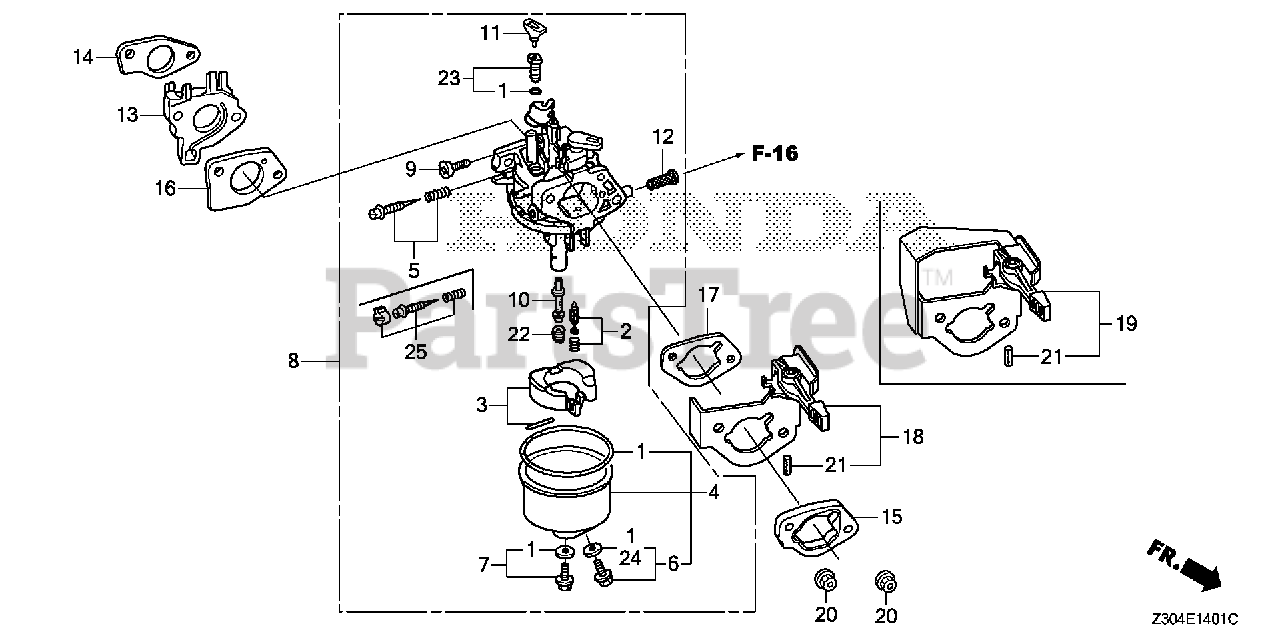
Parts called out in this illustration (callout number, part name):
1	GASKET SET
2	VALVE SET, FLOAT
3	FLOAT SET (CARBURETOR NO.)
4	CHAMBER SET, FLOAT
6	SCREW SET, DRAIN (Honda Code 1672187). (CARBURETOR NO.)
7	SCREW SET
8	CARBURETOR ASSY. (BE95L A)
9	SCREW, THROTTLE STOP
10	NOZZLE, MAIN
11	COLLAR, SET
12	SCREEN, FUEL STRAINER
13	INSULATOR, CARBURETOR
14	GASKET, CARBURETOR INSULATOR
15	SPACER, CARBURETOR
16	GASKET, CARBURETOR
17	GASKET, AIR CLEANER
18	BASE, CHOKE
20	NUT, FLANGE (6MM)
21	PIN, SPRING (2X12)
22	JET, MAIN (#100) Use from Engine SN BE87A A to BE87A A.
22	JET, MAIN (#102) (ADVENTURE GREEN) (CARBURETOR NO.)
22	JET, MAIN (#108) (CARBURETOR NO.)
23	JET SET, PILOT (#38)
24	WASHER, PLAIN (6.2X10.7 DRAIN) (CARBURETOR NO.)
25	SCREW SET (Honda Code 4219879). (CARBURETOR NO.)
